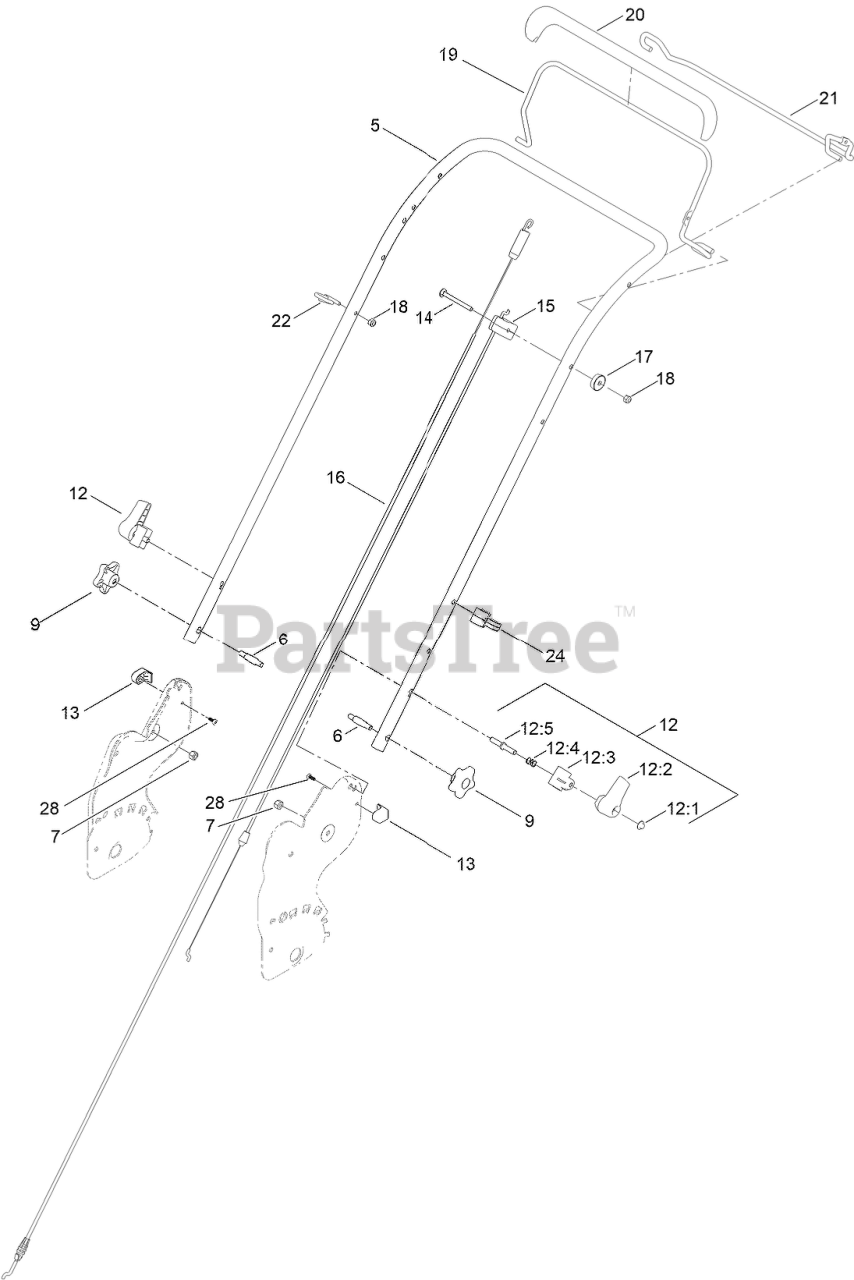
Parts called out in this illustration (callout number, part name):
5	HANDLE-CURVED
6	BOLT-SHOULDER, HANDLE
7	NUT-LOCK, NI
9	KNOB-HANDLE
12	QUICK RELEASE ASM
12:1	NUT-PUSH
12:2	LEVER-RELEASE
12:3	ANCHOR-SPRING
12:4	SPRING-COMPRESSION
12:5	ROD-RELEASE
13	PAD-SMART STOW
14	SCREW-CARR
15	CABLE-BRAKE, FWD
16	CABLE-TRACTION, FWD
17	WASHER-CURVED
18	NUT-LOCK, NI
19	BAIL-BRAKE
20	COVER-BAIL
21	BAIL-TRACTION
22	GUIDE-ROPE
24	GUIDE-CABLE
28	SCREW-PLASTITE
